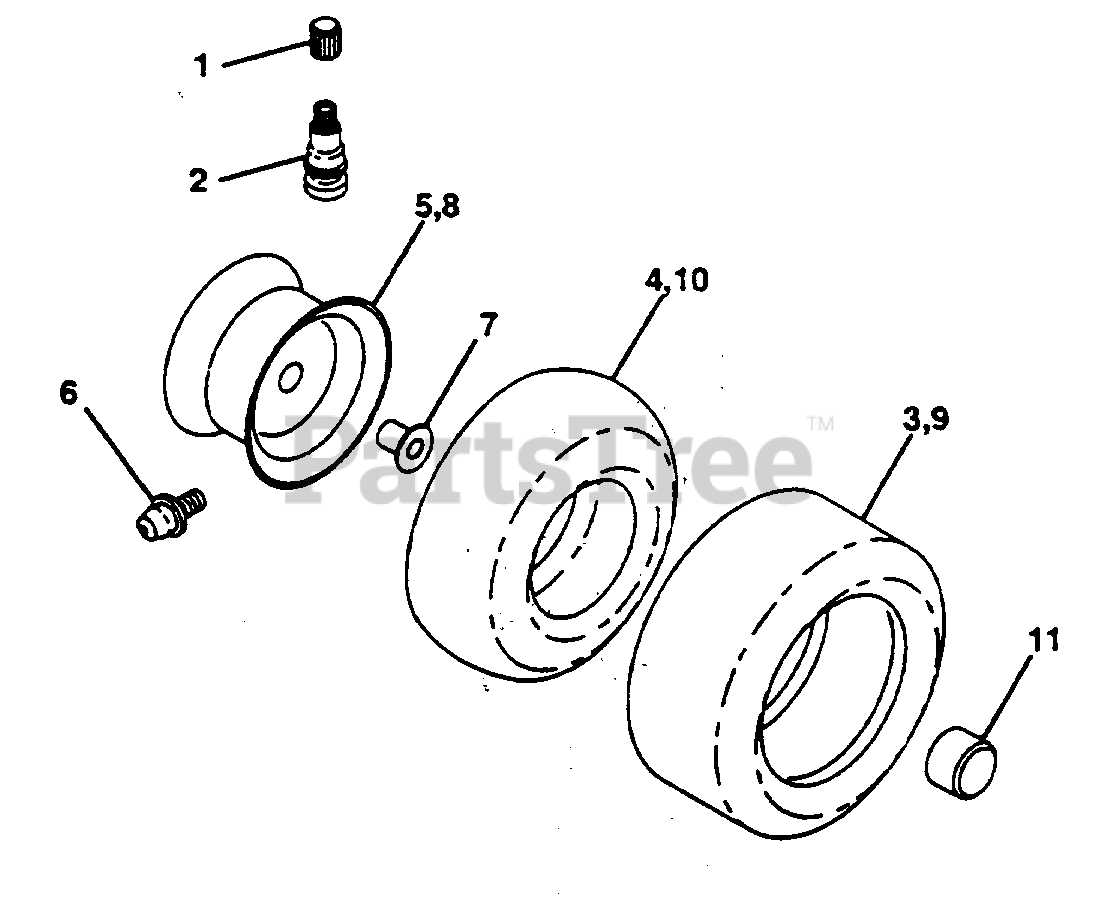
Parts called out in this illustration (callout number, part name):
1	Cap Valve Tire (AYP part number)
2	Stem Valve (AYP part number)
3	Tire F Ts 15 X 6 0 - 6 Service (AYP part number)
4	Tube Front (Service Item Only)
5	Rim Asm 6"front Silver Service (AYP part number)
6	Fitting Grease (Front Wheel Only) (AYP part number)
7	Bearing Flange (Front Wheel Only) (AYP part number)
8	Rim Asm 8"rear Silver Service (AYP part number)
9	Tire R Ts Service (AYP part number)
10	Tube Rear (Service Item Only) (AYP part number)
11	Cap Axle Blk 1 50 X 1 00 (AYP part number)
